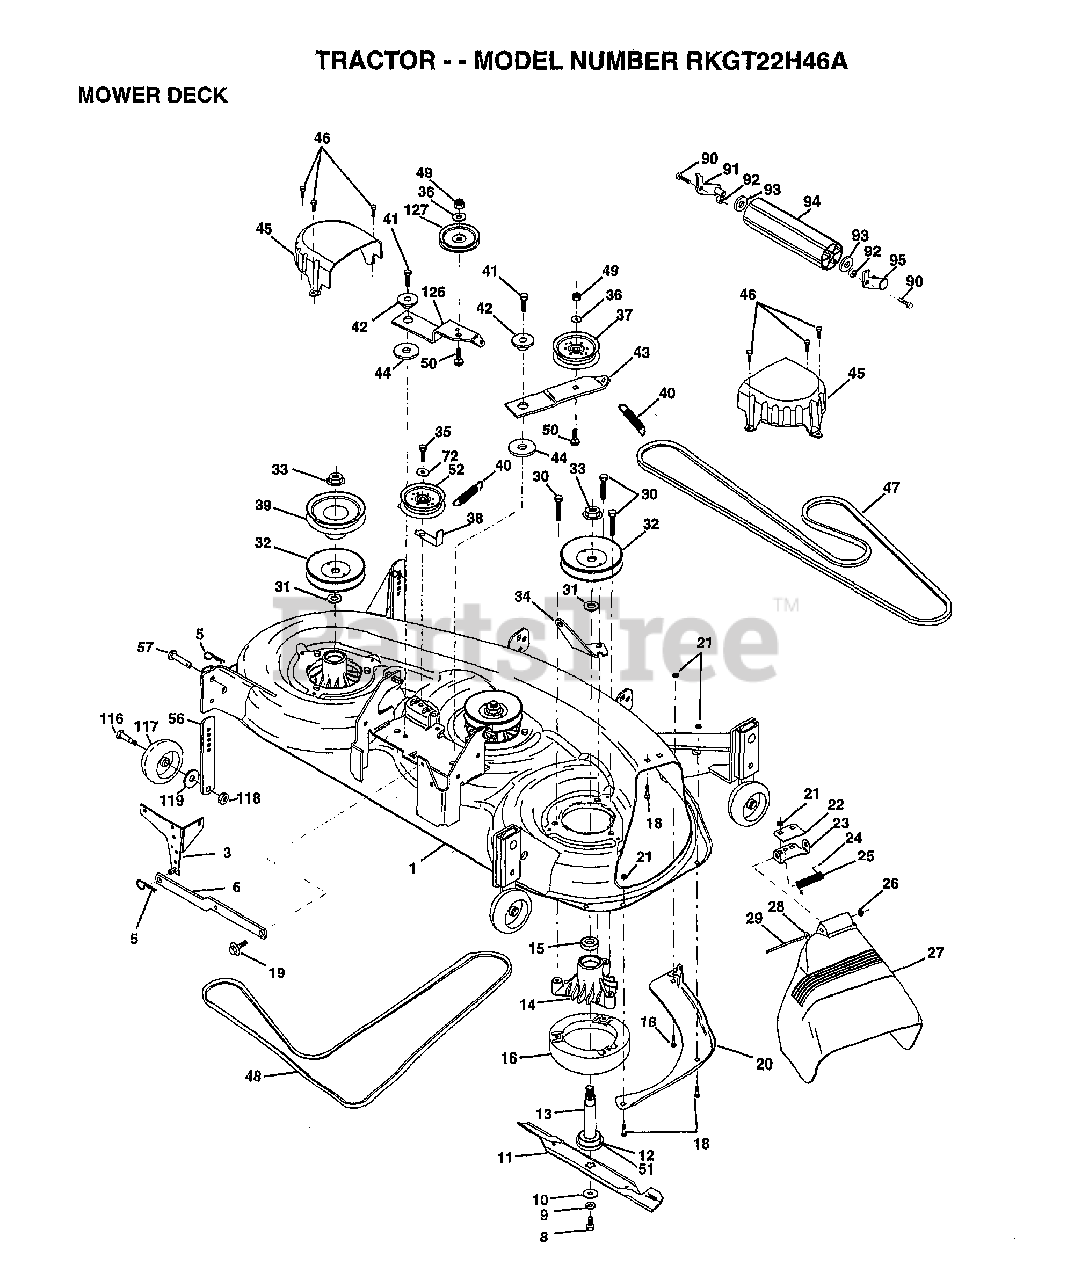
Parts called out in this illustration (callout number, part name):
1	DECK.WELDMENT.MOWER
3	BRKT.ASM.SW.44/50
8	BLADE BOLT
10	WASHER.HARD.BLADE
11	"BLADE.HIGHLIFT46"""
12	BEARING.BALL
13	SHAFT.ASM.W/BRNG
14	HOUSING.MAND.44.V
15	BEARING
16	STRIPPER RND MWR
18	BOLT
19	BOLT SHD 5/16-18
20	BAFFFLE.VORTEX.46
22	STIFFENER BRKT
23	DEFLECTOR BRKT
24	CAP-SLEEVE LT
26	NUT PUSH M
27	SHIELD DEFLECTOR
28	WASHER
29	HINGE ROD
30	"SCREW-THD ROLL,WA"
31	WASHER
32	PULLEY.MAND.36/46
34	ANCHOR.SPRING.46
35	SCREW LT
36	WASHER
38	"KEEPER BELT,IDLER"
39	PULLEY.DRV.DCK.46
40	"SPRING.SEC.44""VEN"
41	SCREW
42	SPACER RETAINER
43	ARM.IDLER.DECK.46
44	HARDENED WASHER
45	COVER.MANDREL.46
46	SCREW.1/4-20X5/8
47	BELT-V.SEC.46.KEL
48	BELT.MWR.PRM.85.4
50	BOLT.3/8-16X1.50
51	WASHER.FELT.
52	"PULLEY IDLER,FLAT"
57	RIVET-PAN HEAD
72	WASHER HYT
90	BOLT
92	NUT
93	WASHER
116	BOLT.SHOULDER
117	WHEEL GAGE DONUT
118	LOCKNUT
119	WASHER
126	ARM.IDLER.PRIM.46
127	PULLEY.IDLER.4.25
